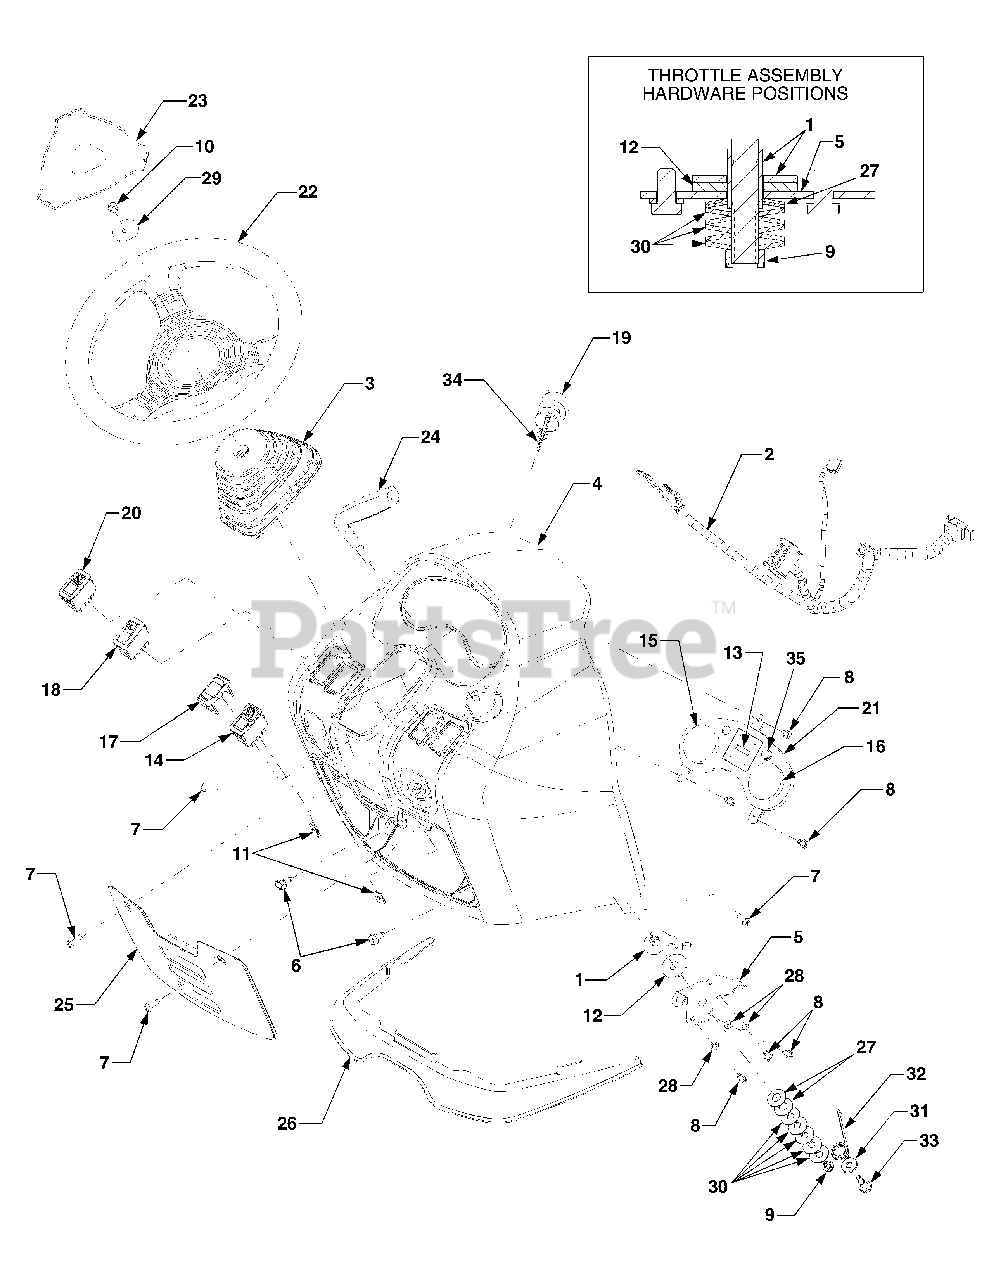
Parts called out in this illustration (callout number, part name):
1	Bracket, Throttle Cable
2	Wire Harness, Dash
3	Boot, Steering Shaft
4	Dash
5	Bracket, Throttle Mtg.
6	Screw, Hex Wash. Hd. Tapp 5/16-18 x .625
7	Screw, Pan Hd., 1/4-20 x .75
8	Screw, Hex Cap, 1/4-20 x .5 GR5
9	Nut, Hex Insert Jam Lock, 3/8-24 ..
10	Nut, Hex Lock, 5/16-24
11	Nut, Speed, 1/4-20
12	Washer, Friction, .515 x 1.5 x .12 ..
13	Meter, Hour/Indicator
14	Switch, PTO
15	Gauge, Fuel
16	Gauge, RPM
18	Switch, Headlight
19	Switch, Ignition
20	Switch, Hazard
21	Panel, Meter
22	Steering Wheel, Soft Grip
23	Cover, Steering Wheel
24	Handle, Throttle
25	Panel, Dash Insert
26	Extension, Dash
27	Washer, Belleville, .51 x 1.14 x .04
28	Washer, Lock, 1/4
29	Washer, Flat, .344 x 1.5 x .1
30	Washer, Belleville, .39 x 1.13 x .062
31	Washer, Flat, .38 x .93 x .110 Hdn
32	Spring, Torsion
33	Screw, Shoulder, .374 x .56
34	Key Set, Ingition
35	Lamp, Yellow Panel
